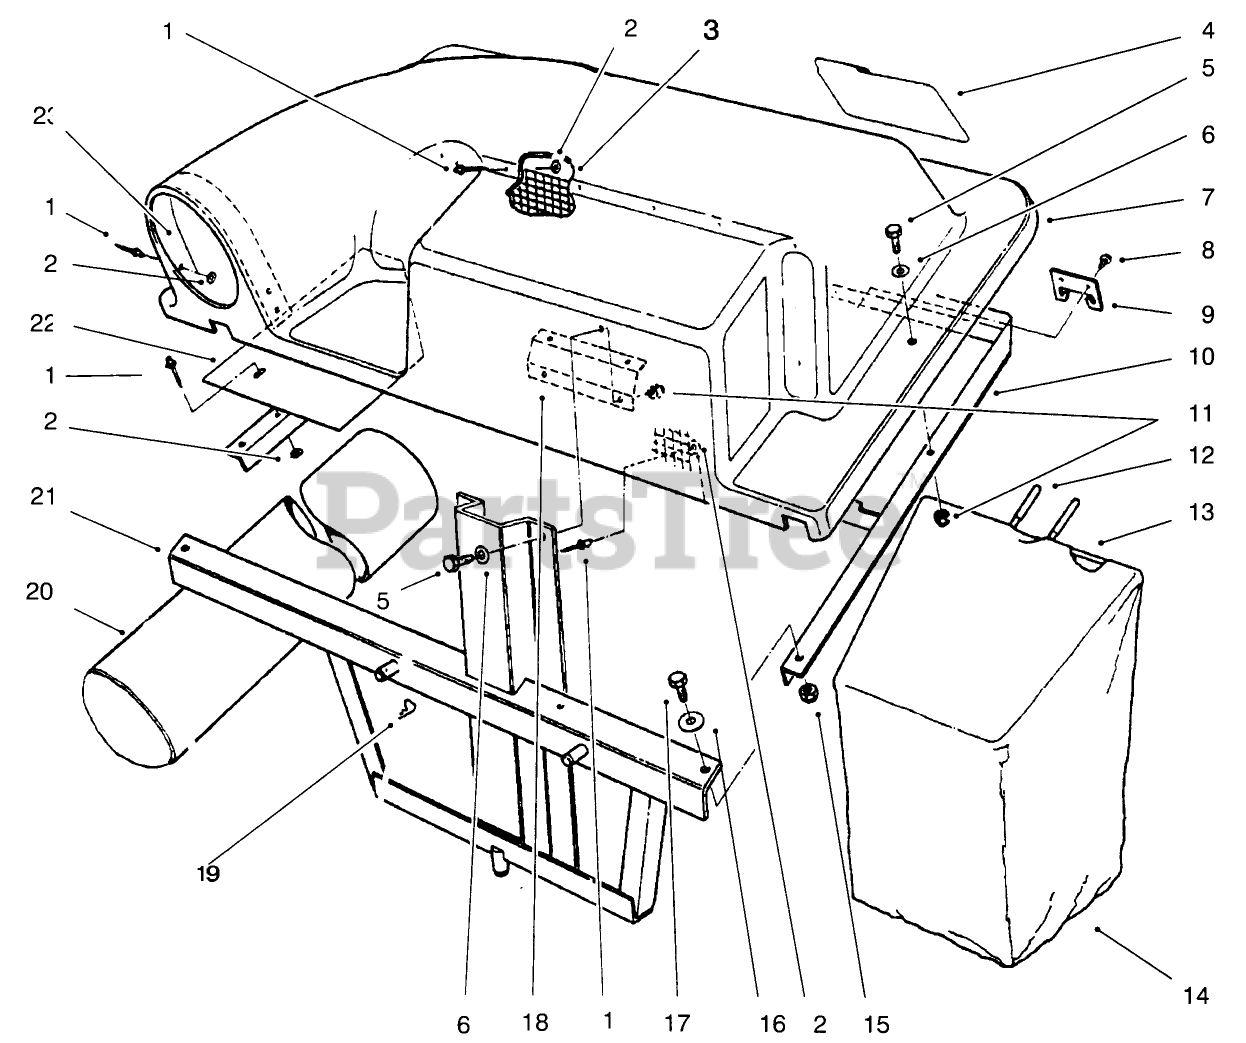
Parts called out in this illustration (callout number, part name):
1	RIVET-POP
2	WASHER-PLAIN
3	SCREEN
4	DECAL-BAGGER, TWIN
5	SCREW-HH
6	WASHER-PLAIN
7	COVER-BAGGER, TWIN
8	SCREW-HWH
9	BRACKET-FRAME, BAG
11	NUT-LOCK, NI
12	GRIP-HANDLE, BAG
15	NUT-LOCK, NI
16	WASHER-FLAT
17	SCREW-HH
19	PIN-HAIR
20	DUCT-BAGGER
